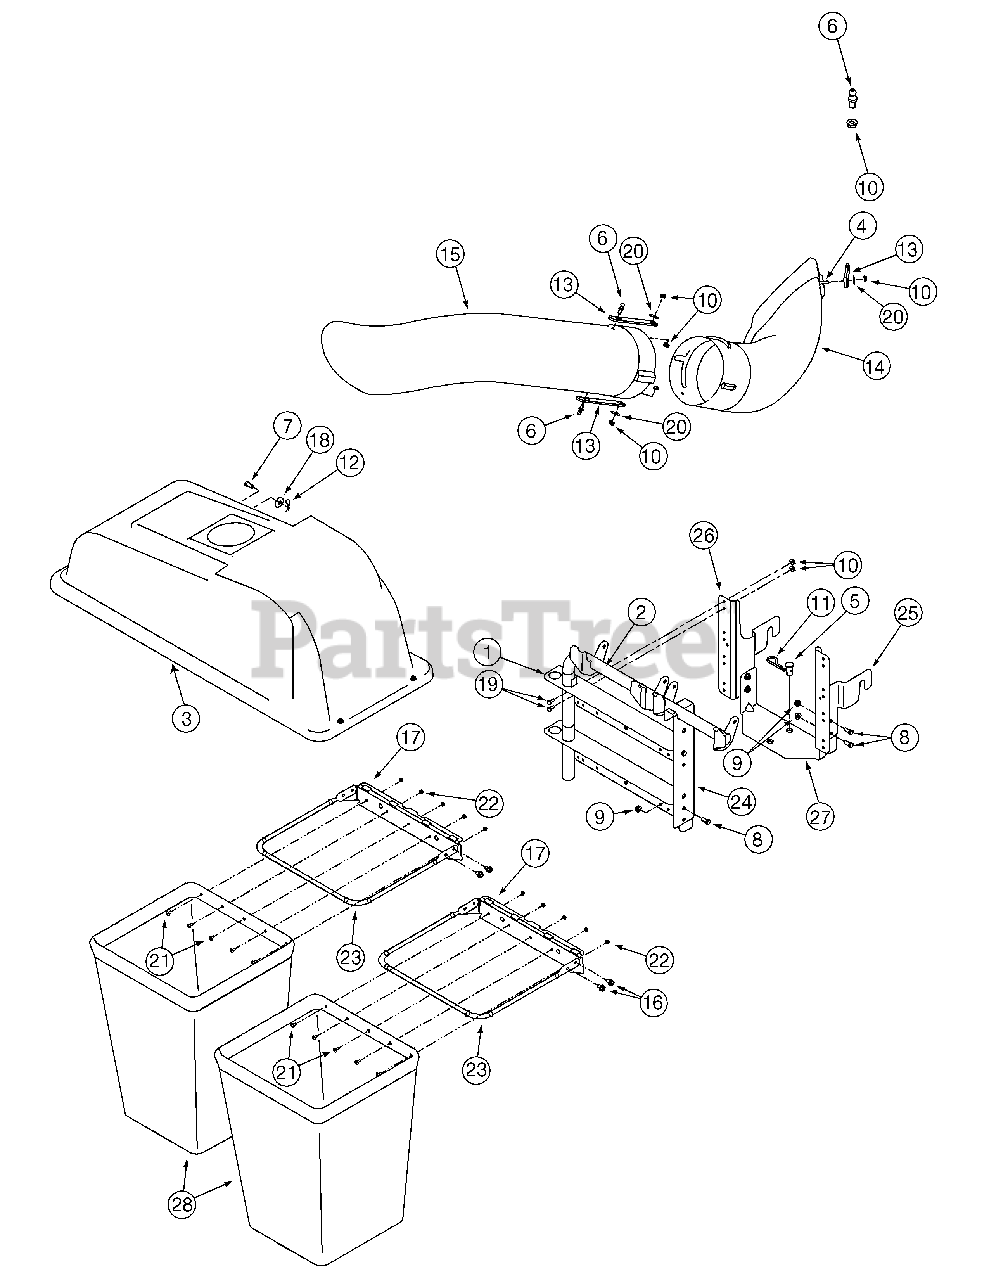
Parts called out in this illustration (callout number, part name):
3	Grass catcher Cover Assembly
4	Screw 1/4-20 x 1"
5	Clevis Pin
6	Grass Catcher Pin 1/4-20
7	Clevis Pin
8	Hex Head Screw 5/16-18 x .75
9	Lock Nut 5/16-18
10	Hex Flange Lock Nut, 1/4-20
11	Hairpin Clip
12	Click Pin
13	Chute Strap
14	Discharge Chute 38"/42" Bag
15	Chute Tube
16	Self-Tapping Screw 5/16-18
18	Bell Washer
19	Hex Head Screw 1/4-20 x .62
20	Flat Washer
21	Machine Screw, , #10-24 x .5
22	Hex Sems Nut, #10-24
28	Catcher Bag
